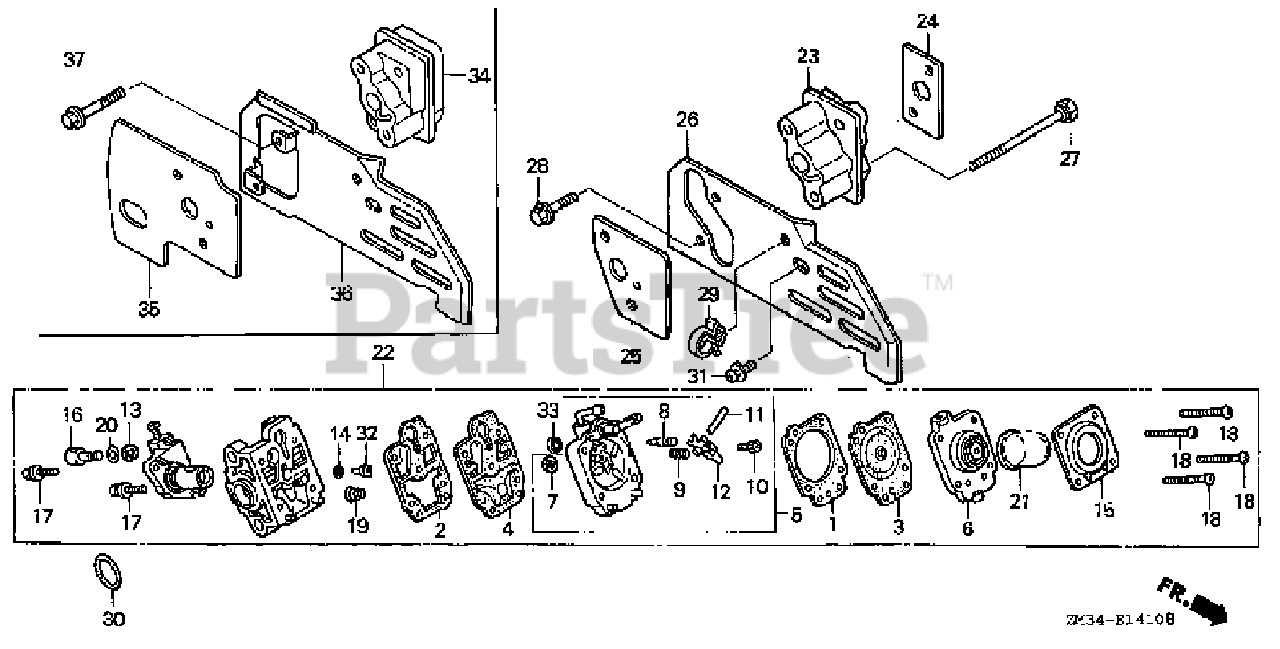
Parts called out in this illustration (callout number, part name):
1	GASKET, METERING DIAPHRAGM
2	GASKET, PUMP
3	DIAPHRAGM ASSY., METERING
4	DIAPHRAGM, PUMP
5	BODY ASSY., PUMP
6	BODY ASSY., AIR PURGE
7	SCREEN, INLET
8	VALVE, IN. NEEDLE
9	SPRING, METERING LEVER
10	SCREW, METERING LEVER PIN
11	PIN, METERING LEVER
12	LEVER, METERING
13	RING, SPRING RETAINING
14	O-RING
15	COVER, PRIMER PUMP
16	SWIVEL
17	SCREW, THROTTLE COLLAR
18	SCREW, PUMP COVER
19	SPRING, PUMP
20	WASHER
21	PUMP, PRIMER
22	CARBURETOR ASSY. (WYL-83A)
22	CARBURETOR ASSY. (WYL 98A)
22	CARBURETOR ASSY. (WYL 132)
22	CARBURETOR ASSY. (WYL-99)
22	CARBURETOR ASSY. (WYL-99A)
23	INSULATOR, CARBURETOR
24	GASKET, INSULATOR
25	GASKET, CARBURETOR
26	GUIDE, AIR IN.
27	BOLT, HEX. (5X75)
28	BOLT, FLANGE (5X22)
29	CLIP, WIRE HARNESS
30	O-RING (14.8X2.4)
31	SCREW-WASHER (5X10)
32	JET (#31.5)
32	JET (#32.5)
32	JET (#33.5)
32	JET (#34)
32	JET (#35)
32	JET (#36)
32	JET (#37)
32	JET (#38)
33	FILTER, FUEL INLET
34	INSULATOR, CARBURETOR
35	GASKET, CARBURETOR
36	GUIDE, AIR IN.
37	BOLT, FLANGE (5X32)
